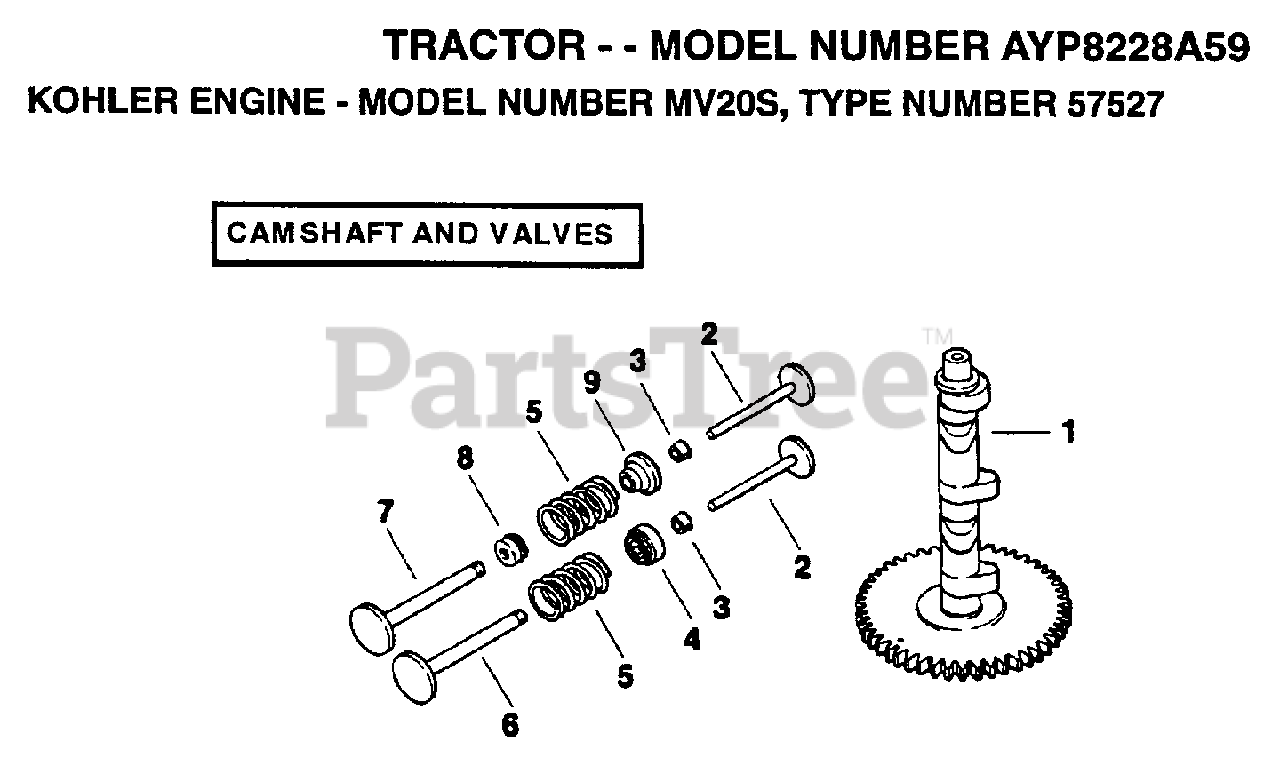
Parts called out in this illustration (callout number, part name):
6	VALVE EXHAUST
7	VALVE, INTAKE
9	RETAINER, INTAKE VALVE
